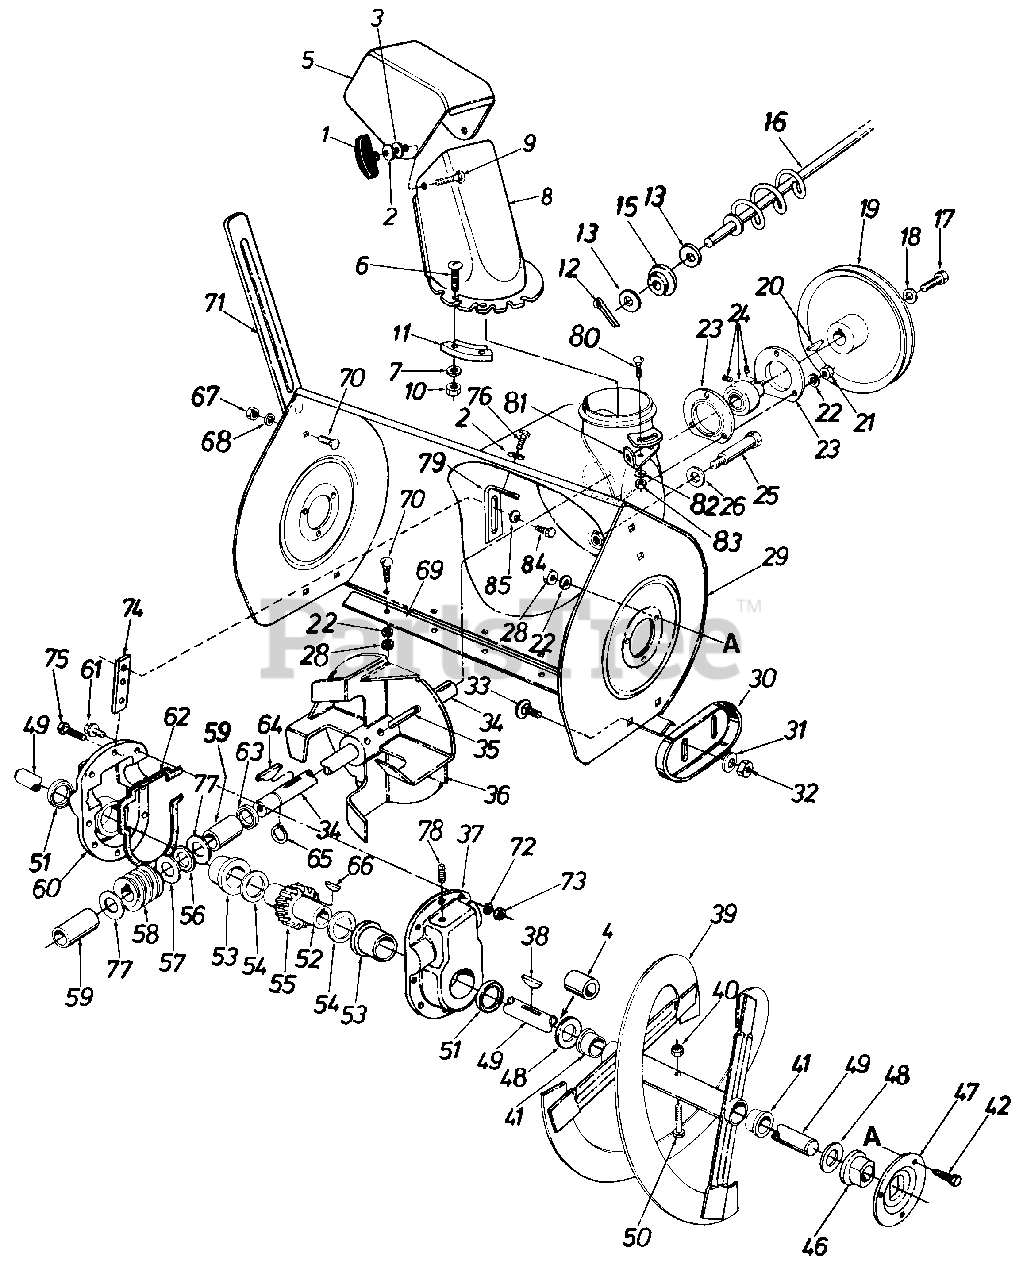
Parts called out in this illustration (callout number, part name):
1	Hand Knob Ass'y.
2	Bell-Wash. .345 I.D. x .88 O.D. x .060
3	Fl. Wash. .312 I.D. x 1.125 O.D. x .125
4	Spacer
5	Top Chute
6	Truss Mach. Scr. 1/4-20 x 75"
7	Fl-Wash. 1/4" I.D.
9	Carr. Bolt 5/16-18 x 1.00" Lg.
10	Hex Cent. L-Nut 1/4-20 Thd.
11	Chute Flange Keeper
12	Cotter Pin
13	Fl-Wash. .385" I.D. x .62"
15	Bushing
16	Chute Crank Ass'y.
17	Hex L-Scr. 5/16-18 x .88" Lg.
18	Bell-Wash. .345 I.D. x .88
19	V-Pulley .875 I.D. x 10.12
20	#9 Hi-Pro Key 3/16 x 3/4" Dia.
21	Hex Nut 5/16-18 Thd.*
22	L-Wash. 5/16" I.D.*
23	Bearing Hsg.-Self Aligning Brg.
24	Self Aligning Brg. .875 I.D.
25	Stud 3/8-16 x 2.75" Lg.
26	Bell-Wash. .400 I.D. x .88 0 O.D. x .060
28	Hex Nut 5/16-18 Thd.*
29	Blower Hsg. Ass'y.
30	Slide Shoe
31	Bell-Wash. .400 I.D. x .88 O.D. x .060
32	Hex Jam Nut 3/8-16 Thd.
33	Carr. Bolt 3/8-16 x .62" Lg.
34	Blower Axle
35	Spring Pin Spiral 5/16" Dia. x 1.75" Lg.
38	#91 Woodruff Key 1/4" x 3/4" Dia.
41	Plastic Bushing
42	Hex Sems Scr. 5/16-18 x .75"
46	Flange Brg. w/Flats 1.0" I.D.
47	Bearing Hsg.-Spiral Hsg.
48	Fl-Wash. 1.06 I.D. x l.75" O.D. x .100
49	Spiral Axle
50	Hex Bolt 5/16-18 x 1.75" Lg.
51	Oil Seal 1.50" I.D.
52	Worm Gear Shaft
53	Flange Brg. 1.503 I.D.
54	Fl-Wash. 1.5 I.D. x 2.0 O.D.
55	Double Threaded Worm Gear
56	Thrust Brg. .88 I.D. x 1.44 O.D. x .078
57	Fl-Wash. .88 I.D. x 1.40 O.D.
58	Double Threaded Worm-L.H.
59	Sleeve Brg. .875 I.D.
60	Complete Gear Hsg. Half-R.H.
61	Hex Bolt 5/16-18 x 1.0" Lg.
62	Gasket
63	Oil Seal .875" I.D.
64	#9 Hi-Pro Key 3/16 x 3/4" Dia.
65	Snap Ring-.875" Dia.
66	#91 Woodruff Key 1/4 x 3/4" Dia.
67	Hex Nut 5/16-18 Thd.*
68	L-Wash. 5/16" I.D.*
69	Shave Plate-28"
70	Carr. Bolt 5/16-18 x .62" Lg.
71	Drift Cutter
72	Wave Wash. 5/16" I.D.
73	Hex Ins. L-Nut 5/16-18 Thd.
74	Gear Hsg. Support Plate
75	Hex Bolt 5/16-18 x 1.25"*
76	Hex Wash. Hd. Self-Tap Scr. 5/16-18 x .75" Lg.
77	Fl-Wash. .88 I.D. x 1.40 O.D.
78	Filler Plug
79	Gear Hsg. Support Brkt.
80	Carr. Bolt 5/16-18 x .75" Lg.
81	Chute Crank Bracket
82	Bell-Wash. .345 I.D. x .88"
83	Hex Nut 5/16-18 Thd.*
84	Hex Bolt 1/4-28 x .75" Lg.
85	Bell-Wash. .28" I.D. x .75" O.D.
